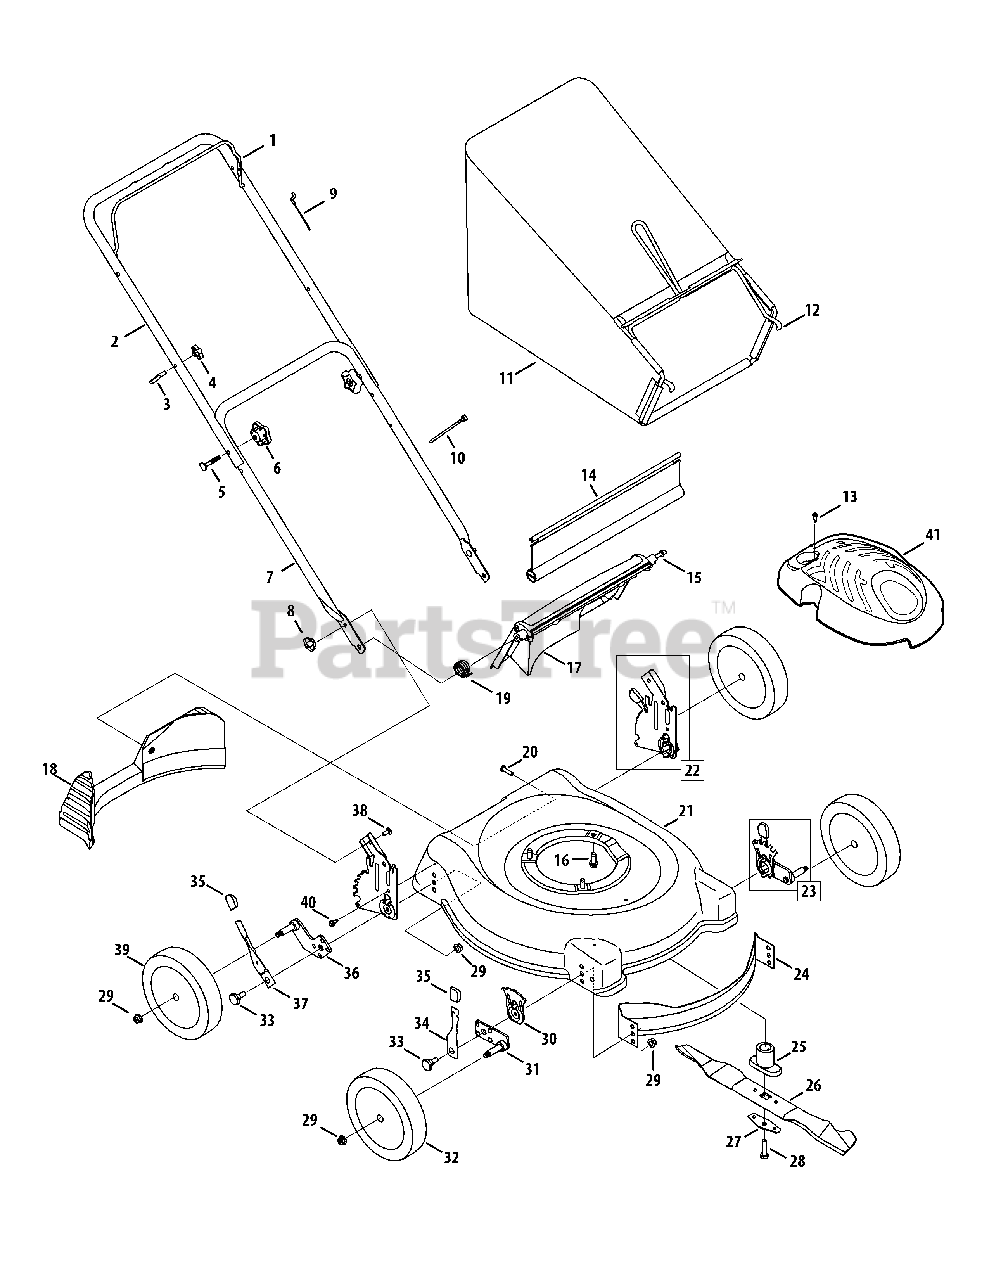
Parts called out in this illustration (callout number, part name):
1	Blade Control
2	Upper Handle
3	Rope Guide
4	Wing Nut, 1/4-20
5	Carriage Bolt, 5/16-18 x 2
6	Hand Star Knob
7	Lower Handle
8	Wing Nut, 1/4-20
9	Control Cable
10	Cable Tie
11	Grass Bag
12	Grass Bag Frame
13	Screw, HL, #12-16 x 1.00
14	Trail Shield
15	Rear Door Pivot Rod
16	TT Screw, 3/8-16 x 1
17	Rear Discharge Door
18	Rear Baffle
19	Torsion Spring RH
20	Screw, 1/4-15 x 1.00
21	Deck 21 inch
22	Handle Bracket Assy - RH
22	Handle Bracket Assy - LH
23	Ht. Adj. Assy. Frt - LH
23	Ht. Adj. Assy. Frt - RH
24	Front Baffle
25	Blade Adapter, #6 x 2.15 w/Star
26	Mulch Blade
27	Blade Bell Support
28	Screw, 3/8-24 x 2.50
29	Flange Lock Nut, 3/8-16
30	Height Adjustment Plate
31	Pivot Arm Assy - RH
31	Pivot Arm Assy - LH
32	Front Wheel, 7 x 1.8
33	Scr., Shldr., .500 Dia. X .385
34	Spring Lever
35	Height Adjustment Knob
36	Pivot Arm Assembly - RH
36	Pivot Arm Assembly - LH
37	Spring Lever
38	Carriage Bolt, 1/4-20
39	Rear Wheel, 8 x 1.8
40	Screw, 1/4-20 x .625
41	Engine Shroud
